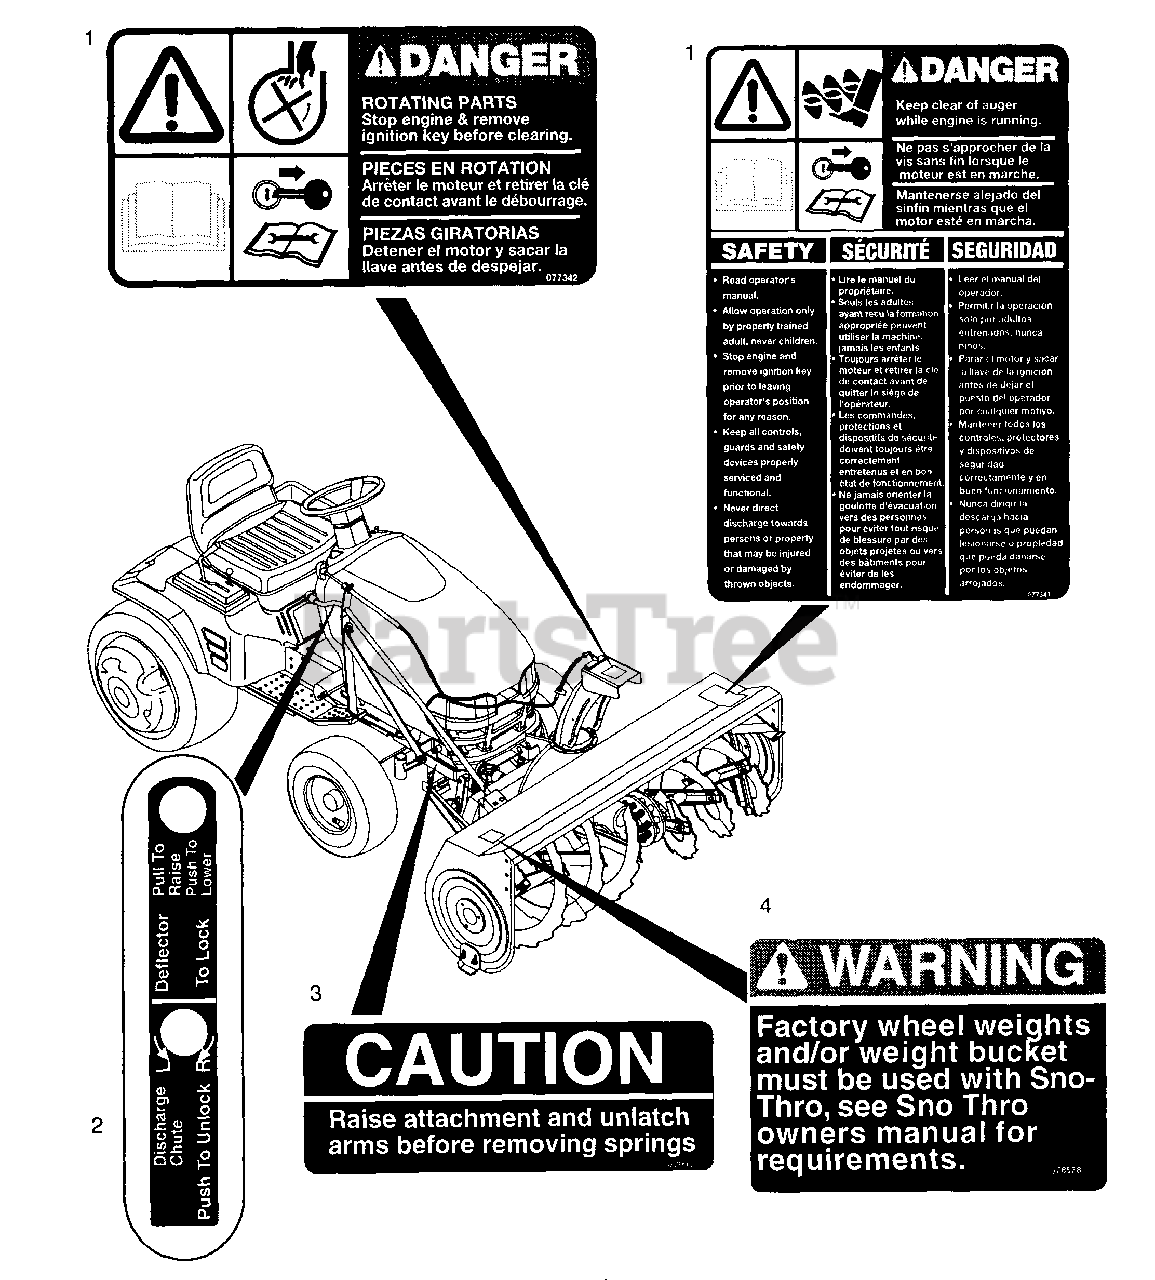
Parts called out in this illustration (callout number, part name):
1	DECAL SET - SNO-HEAD
2	DECAL- CHUTE CRANK
3	DECAL - CAUTION
4	WARNING WHEEL WEIGHT DECAL
